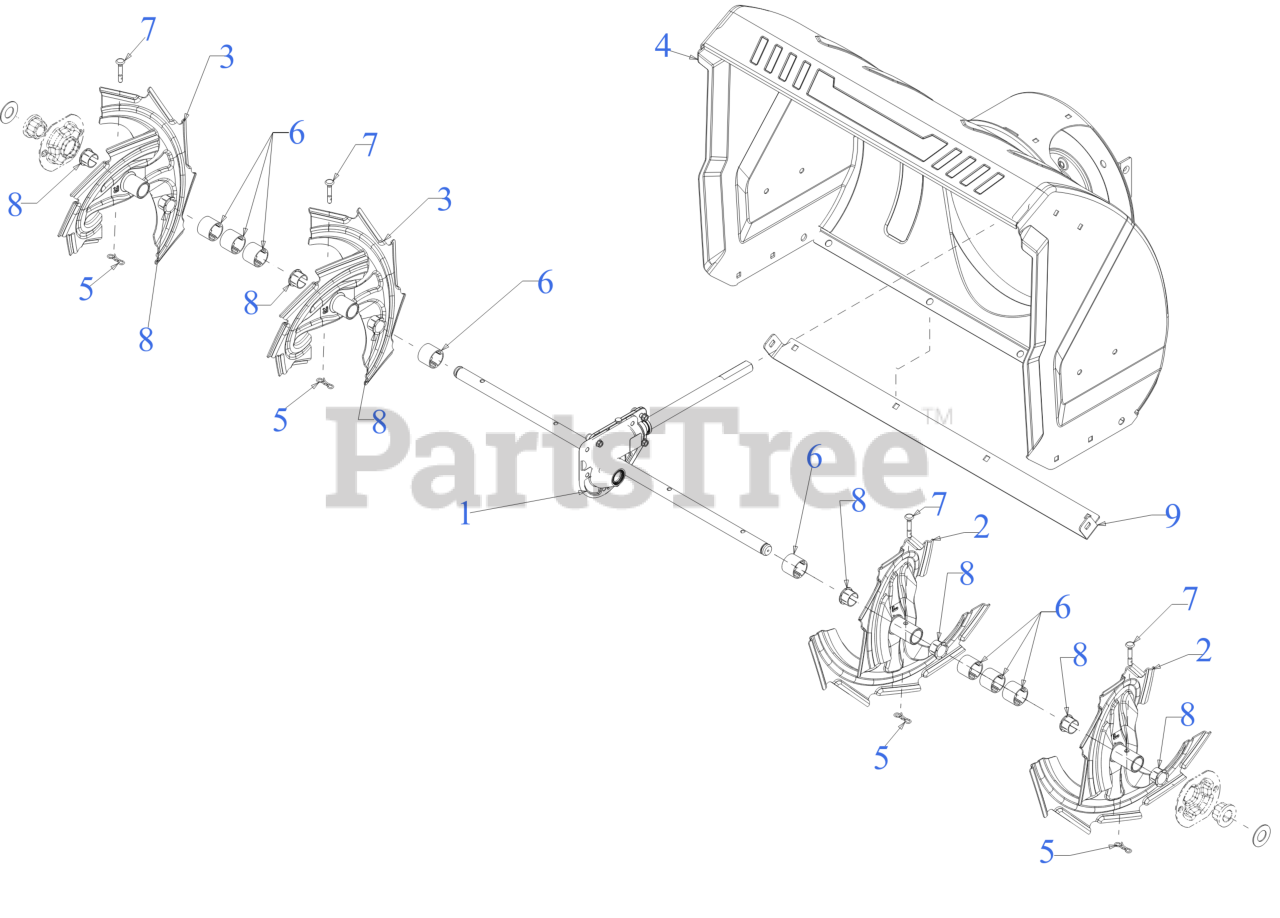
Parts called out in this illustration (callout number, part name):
1	GEARBOX ASSEMBLY 28"
2	10T AUGER SPIRAL (LH)
3	10T AUGER SPIRAL (RH)
4	28" AUGER HOUSING
5	BOW TIE COTTER PIN 1/4-5/16
6	SPACER 1.25OD x .75ID X1.00 LG
7	SHEAR PIN .25 x 1.50 GR2
8	FLANGE BUSHING
9	28" SHAVE PLATE
